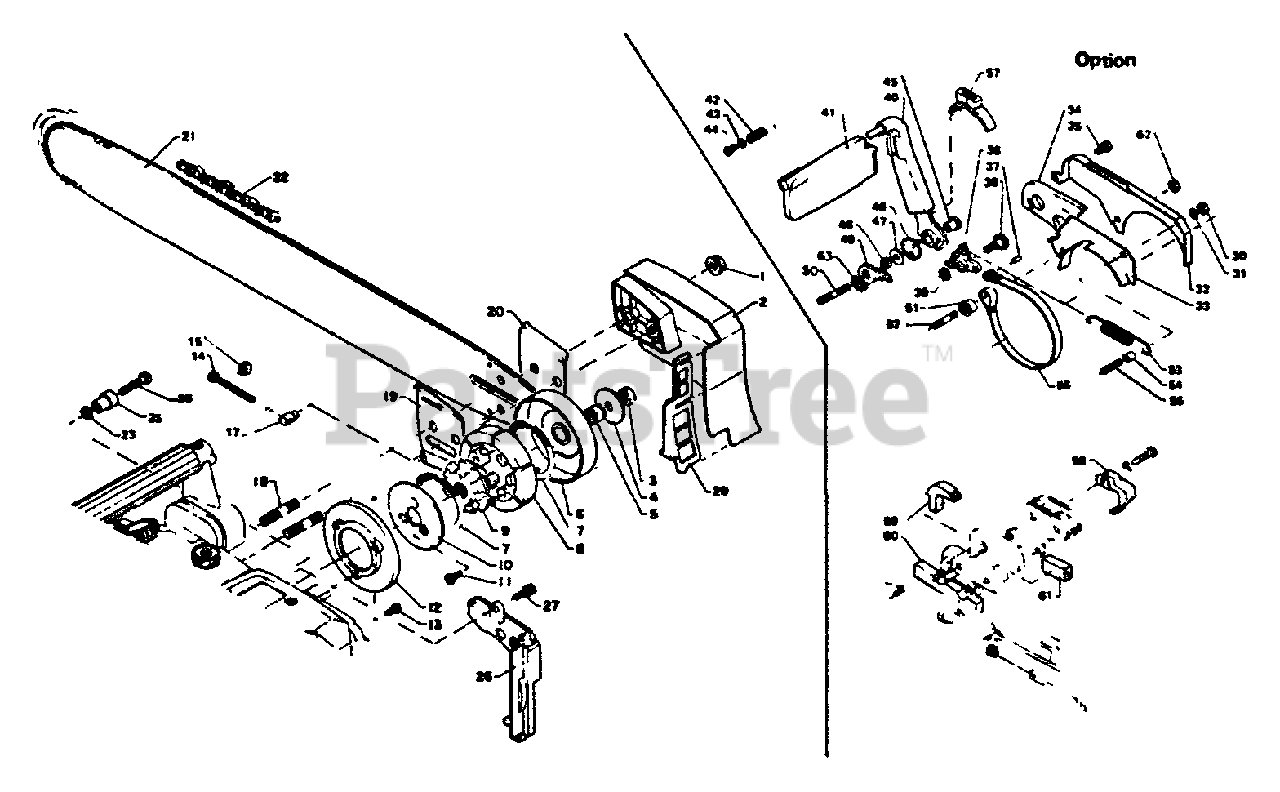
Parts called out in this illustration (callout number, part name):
1	NUT, FLANGE M8×1.25
2	GUARD, SPROCKET
3	LOCKNUT
4	WASHER, CLUTCH
5	BEARING, NEEDLE
6	DRUM, CLUTCH
7	SPRING, CLUTCH
8	SHOE, CLUTCH
9	HUB, CLUTCH
10	PLATE, CLUTCH
11	SCREW - 5×12
12	SEAL, DUST
13	SCREW - 4×10
14	SCREW, ADJUSTER
17	TENSIONER, CHAIN
18	STUD, GUIDE BAR
19	PLATE, SIDE
20	PLATE, SIDE
21	GUIDE BAR
22	CHAIN
23	WASHER, FLAT 5.5×10×0.8
25	CATCHER, CHAIN
26	ADAPTER
27	SCREW 5×14
28	SCREW 5×25
29	PAD
30	NUT M5
31	WASHER, SPRING 5
32	COVER, BRAKE
33	PLATE
34	SEAL
35	SCREW 5×8
36	LEVER, BRAKE
37	PIN, SPRING 4×8
38	BOLT
39	WASHER 6.5×11.5×0.8
39	BRAKE ASSY, CHAIN
40	BRAKE, CHAIN
41	HANDLE, BRAKE - B
42	SPRING
43	WASHER 4 MM
44	SCREW 4×10
45	NUT
46	SPRING, RETURN
47	WASHER
48	SPACER
49	CONNECTOR
50	STUD BOLT
51	ADJUSTER, BRAKE BAND
52	STUD
53	SPRING
54	COLLAR
55	BOLT, STUD
56	BAND, BRAKE
57	COVER, BRAKE
58	SEAL
59	SEAL
60	SEAL
61	SEAL
62	LOCKNUT - 5
63	WASHER
